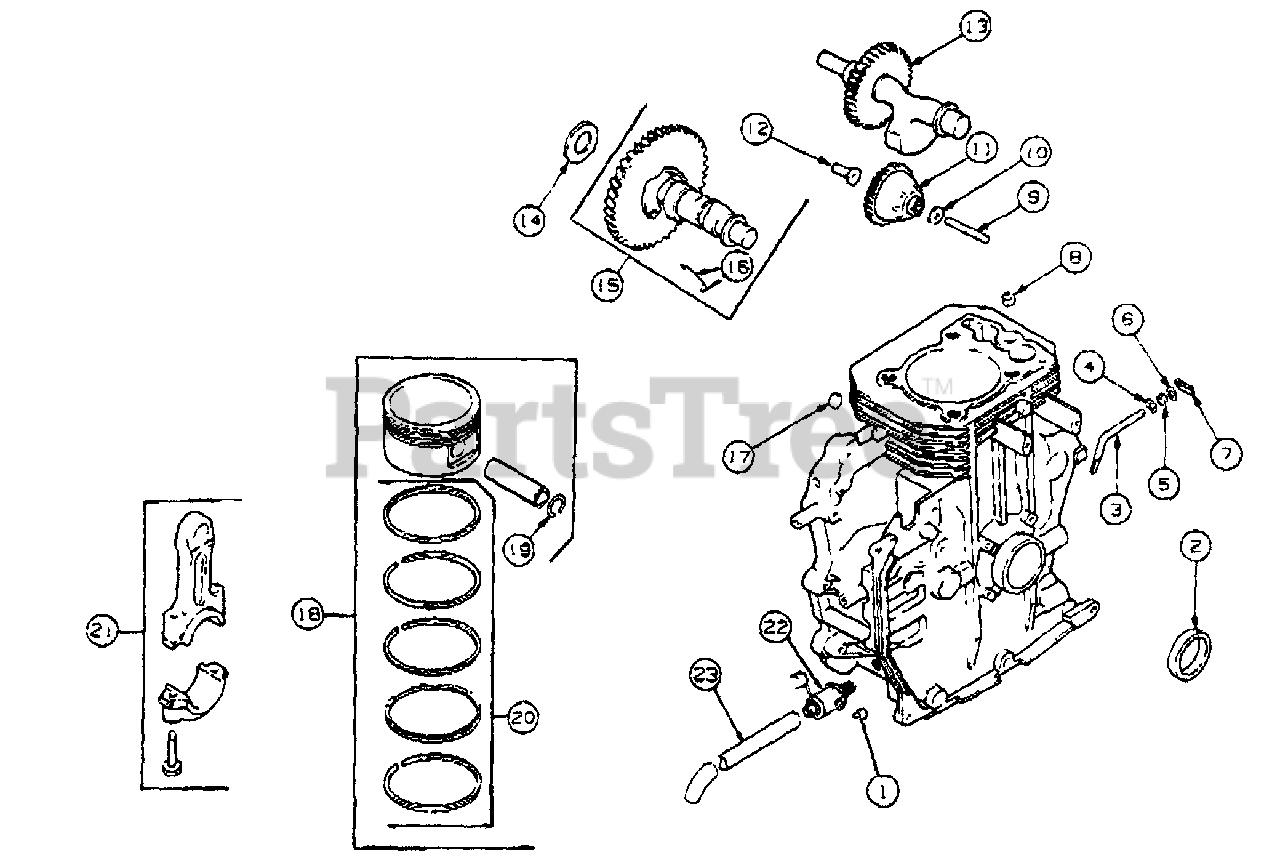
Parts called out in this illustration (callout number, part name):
1	Plug, Solid Sq Head, 3/8 NPTF
2	Seal, Crankshaft
3	Kit, Gov Cross Shaft
4	Washer, Governor Shaft
5	Seal, Governor Cross Shaft
6	Washer, Plain, 1/4
7	Pin, Governor Hitch
8	Dowel, Locating
9	Shaft, Governor Gear
10	Washer, Governor Gear Thrust
11	Gear, Governor Assy
12	Pin, Governor Regulating
13	Shaft, Balance
14	Shim, Camshaft, .0280
15	Camshaft Assy
16	Spring, Actuating
17	Plug, Cup
18	Piston w/Ring Set, Std
19	Retainer, Piston Pin
20	Ring Set, Std
21	Rod, Connecting, Std
22	Drain, Oil
23	Hose, Oil Drain
